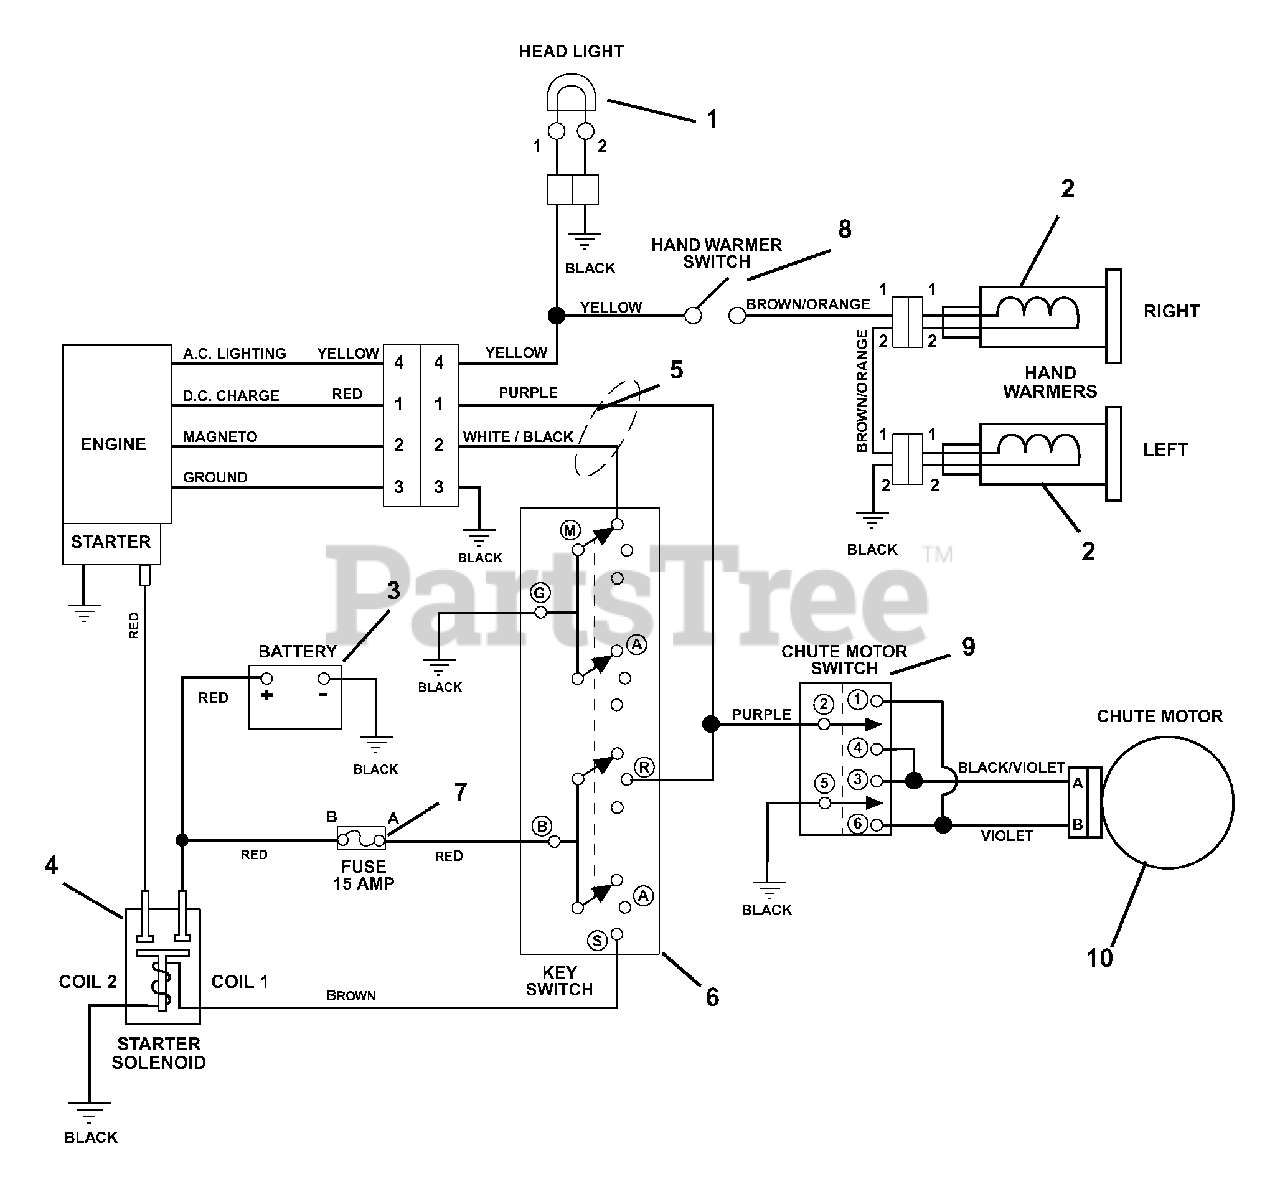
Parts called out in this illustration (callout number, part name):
1	HEADLAMP, OVAL W/ 1156 BULB
2	WARMER, HAND W/TERMINAL
4	SOLENOID
5	HARNESS, WIRE-LT,HW,12V,CHUTE
6	SWITCH ASSEMBLY
7	FUSE, 15 AMP.
8	SWITCH, ON/OFF
9	SWITCH, CHUTE ROTATION
10	MOTOR, ELECTRIC CHUTE
